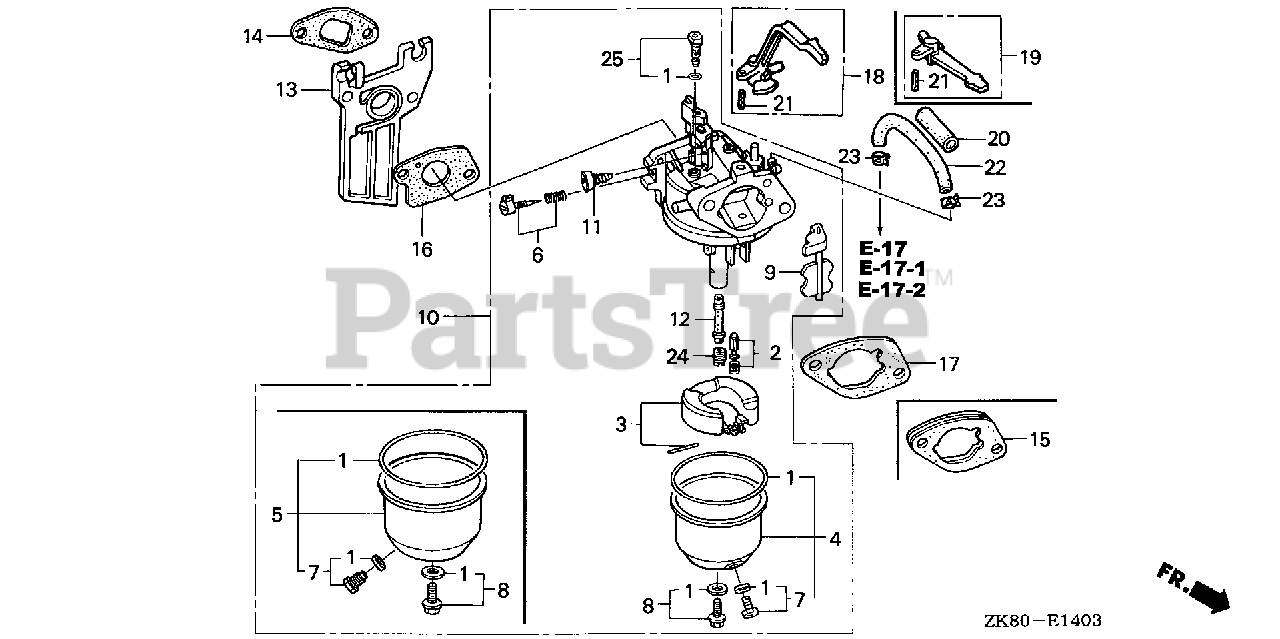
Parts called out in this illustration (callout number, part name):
1	GASKET SET
2	VALVE SET, FLOAT (SEAT NOT INCLUDED)
5	CHAMBER SET, FLOAT
6	SCREW SET, PILOT
7	SCREW SET, DRAIN
8	SCREW SET
10	CARBURETOR ASSY. (BE67C A)
11	SCREW, THROTTLE STOP
12	NOZZLE, MAIN
13	INSULATOR, CARBURETOR
14	GASKET, INSULATOR
15	SPACER, CARBURETOR
16	GASKET, CARBURETOR
19	LEVER, CHOKE (STD)
20	RUBBER, SUPPORTER (107MM)
21	PIN, SPRING (2X12)
22	BULK HOSE, FUEL (4.5X8000) (95001-450(95001-45001-60M)
23	CLAMP, TUBE (D8)
24	JET, MAIN (#65)
24	JET, MAIN (#68)
24	JET, MAIN (#62)
25	JET SET, PILOT (#38)
